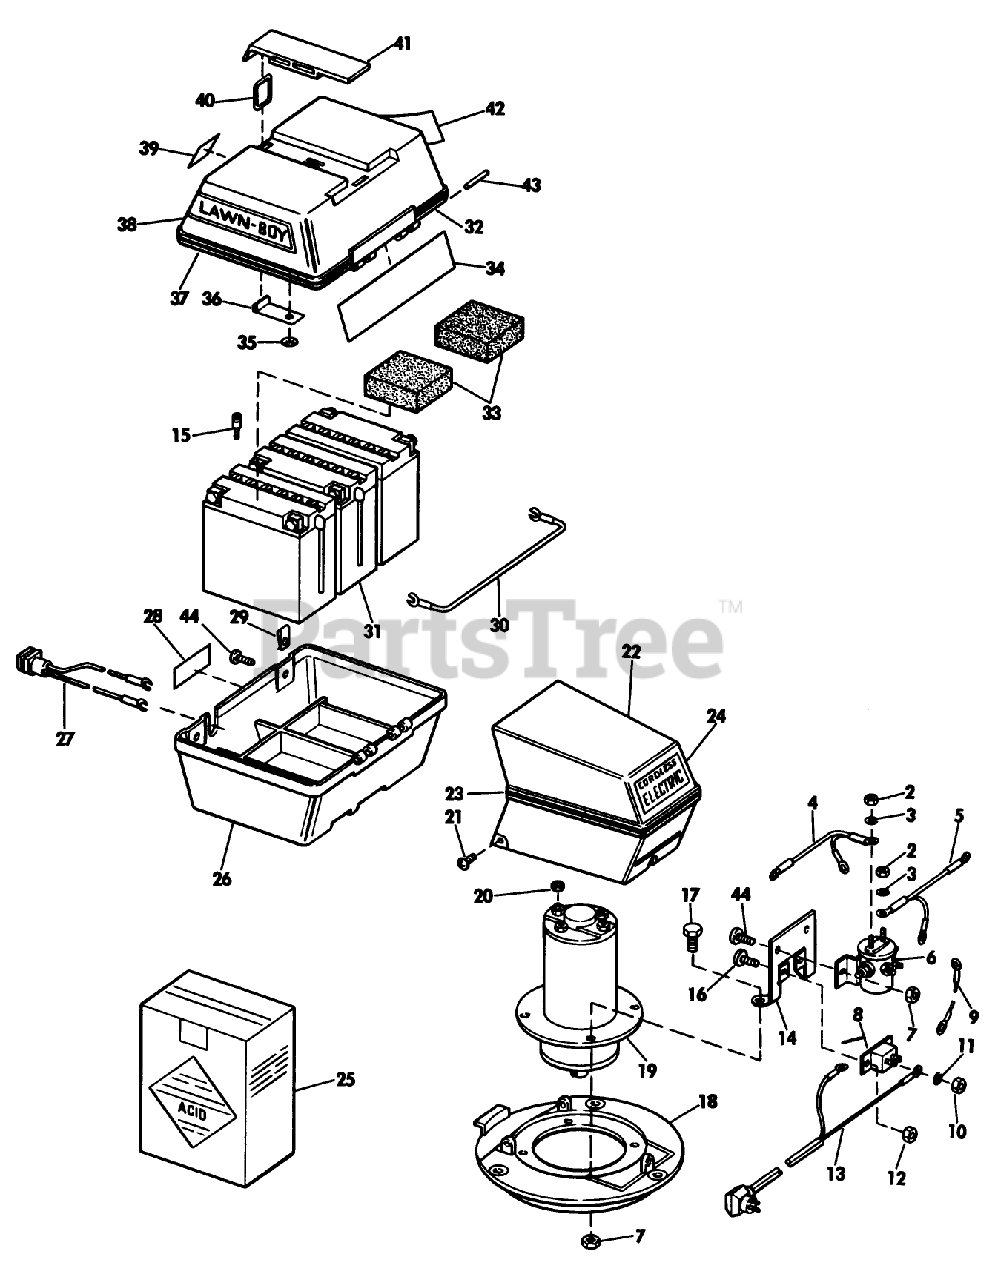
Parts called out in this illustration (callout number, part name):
21	SCREW F
29	SPEED NUT ARDEN
40	Support Ring
